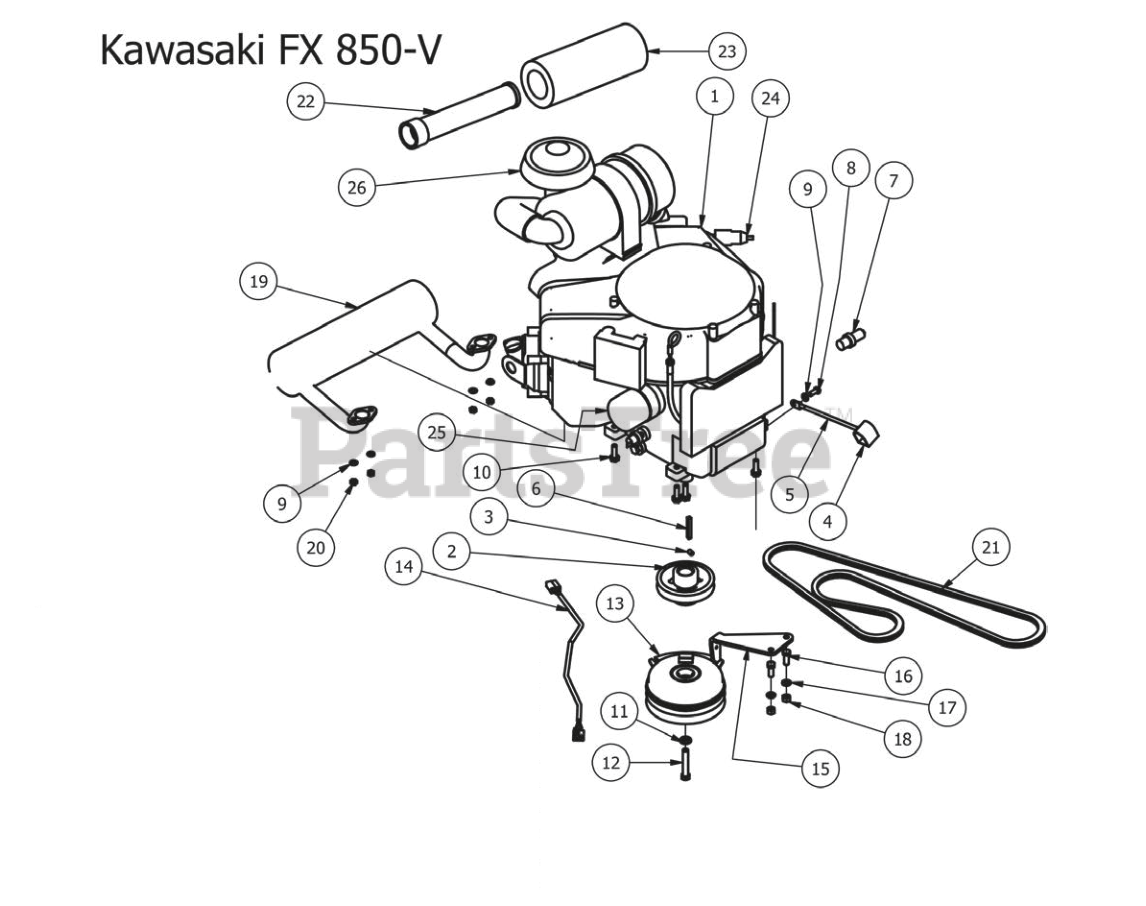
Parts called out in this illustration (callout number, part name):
1	Kawasaki Engine FX-850-V-CS09R
2	4 3/4 Motor Pulley
3	3/8" Set Screw
4	Black Boot For ground cable
5	Starter to chassis cable
6	1/4 x 2 Square key Stock
8	M8x1.20x20MM Hex head bolt
9	5/16" Lock Washer
10	3/8 x 1 1/8 bolt
11	7/16" Lock Washer
12	7/16" x 2 1/2" Hex Bolt
13	Clutch Assembly
14	Clutch Pigtail
15	PTO Engager Holder
16	3/8" x 1" Hex Bolt
17	3/8" Lock Washer
18	3/8" Hex Nut
19	Kawasaki Exhaust
20	M8-1.25 Zinc Nut
22	Canister Air Filter- Inner
23	Canister Air Filter-Outer
24	Universal inline Fuel Filter
25	Kawasaki Oil Filter
26	Rain Cap-Fits all Canisters
